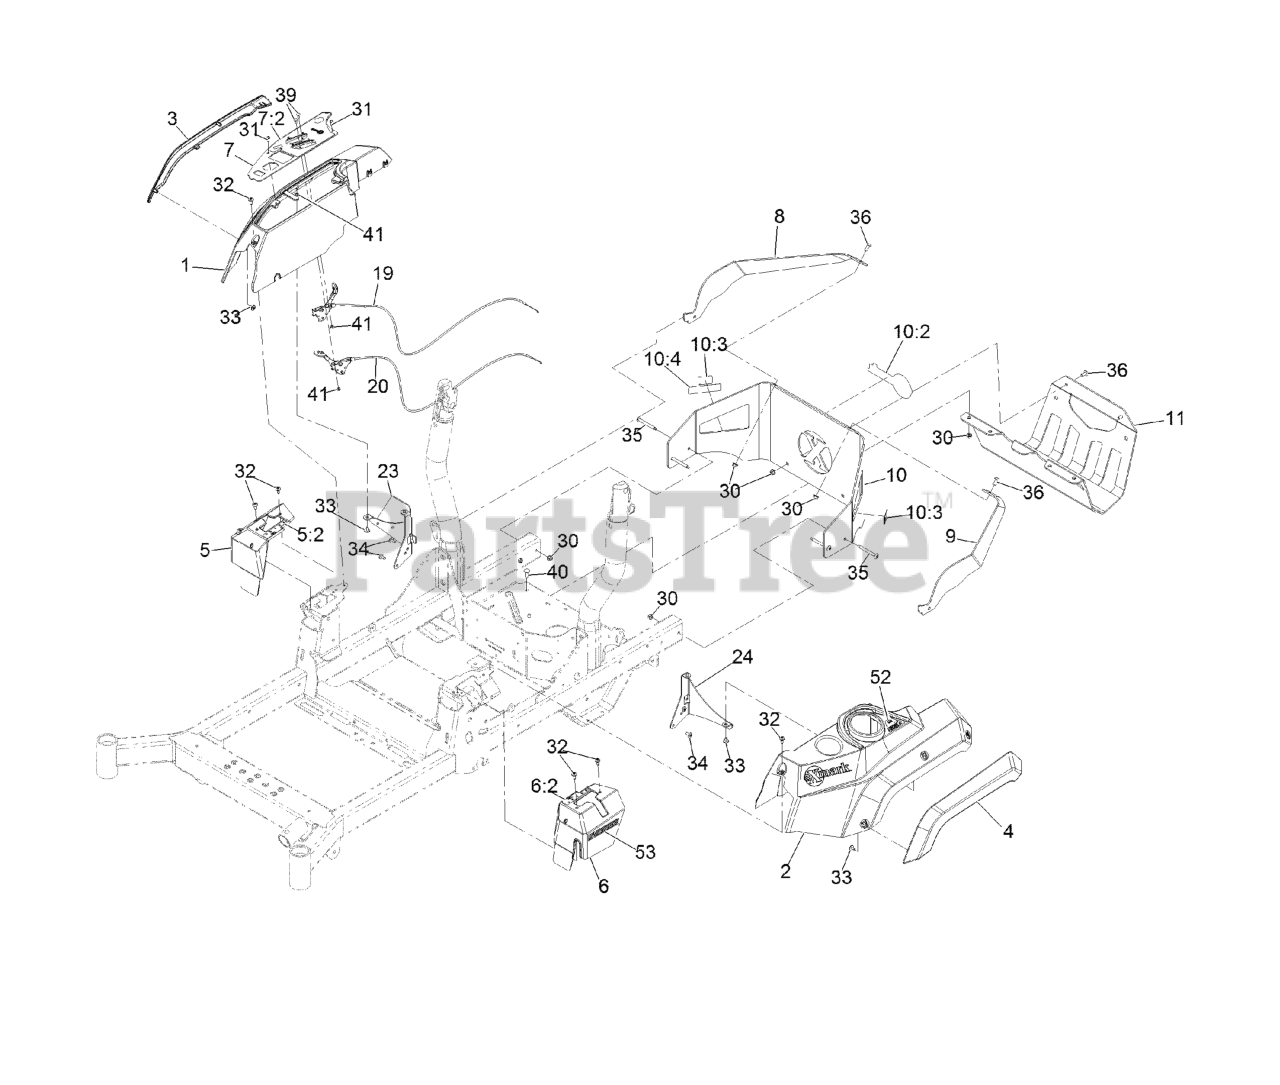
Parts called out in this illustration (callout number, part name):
1	CONSOLE-EXMARK, RH
2	CONSOLE, LH
3	FENDER-RH
4	FENDER-LH
5	COVER-CONTROL, MOTION (RH
5:2	Decal-Control, Motion (RH)
6	COVER-CONTROL, MOTION (LH
6:2	Decal-Control, Motion (LH)
7	ASM-CONTROL PANEL W/EXMARK DECAL
7:2	DECAL-CONTROL PANEL
8	SUPPORT-UPPER, RH
9	SUPPORT-UPPER, LH
10	REAR GUARD ASM
10:2	DECAL, EXMARK LOGO
10:3	DECAL-WARNING
10:4	DECAL-ARRESTOR, SPARK
11	GUARD-MUFFLER
19	CABLE-CONTROL, CHOKE
20	CABLE-CONTROL, THROTTLE
23	SUPPORT-CONSOLE, RH
24	BRACKET-CONSOLE, LH
30	NUT-HF, NI
31	SCREW-HWH
32	SCREW-SHOULDER
33	SCREW-TORX
34	SCREW-TORX
35	SCREW-TORX
36	SCREW-TORX
39	BOLT-CARR
40	SCREW-CARR
41	NUT-LOCK, NI
52	DECAL-FILL, FUEL
53	DECAL-S-SERIES
